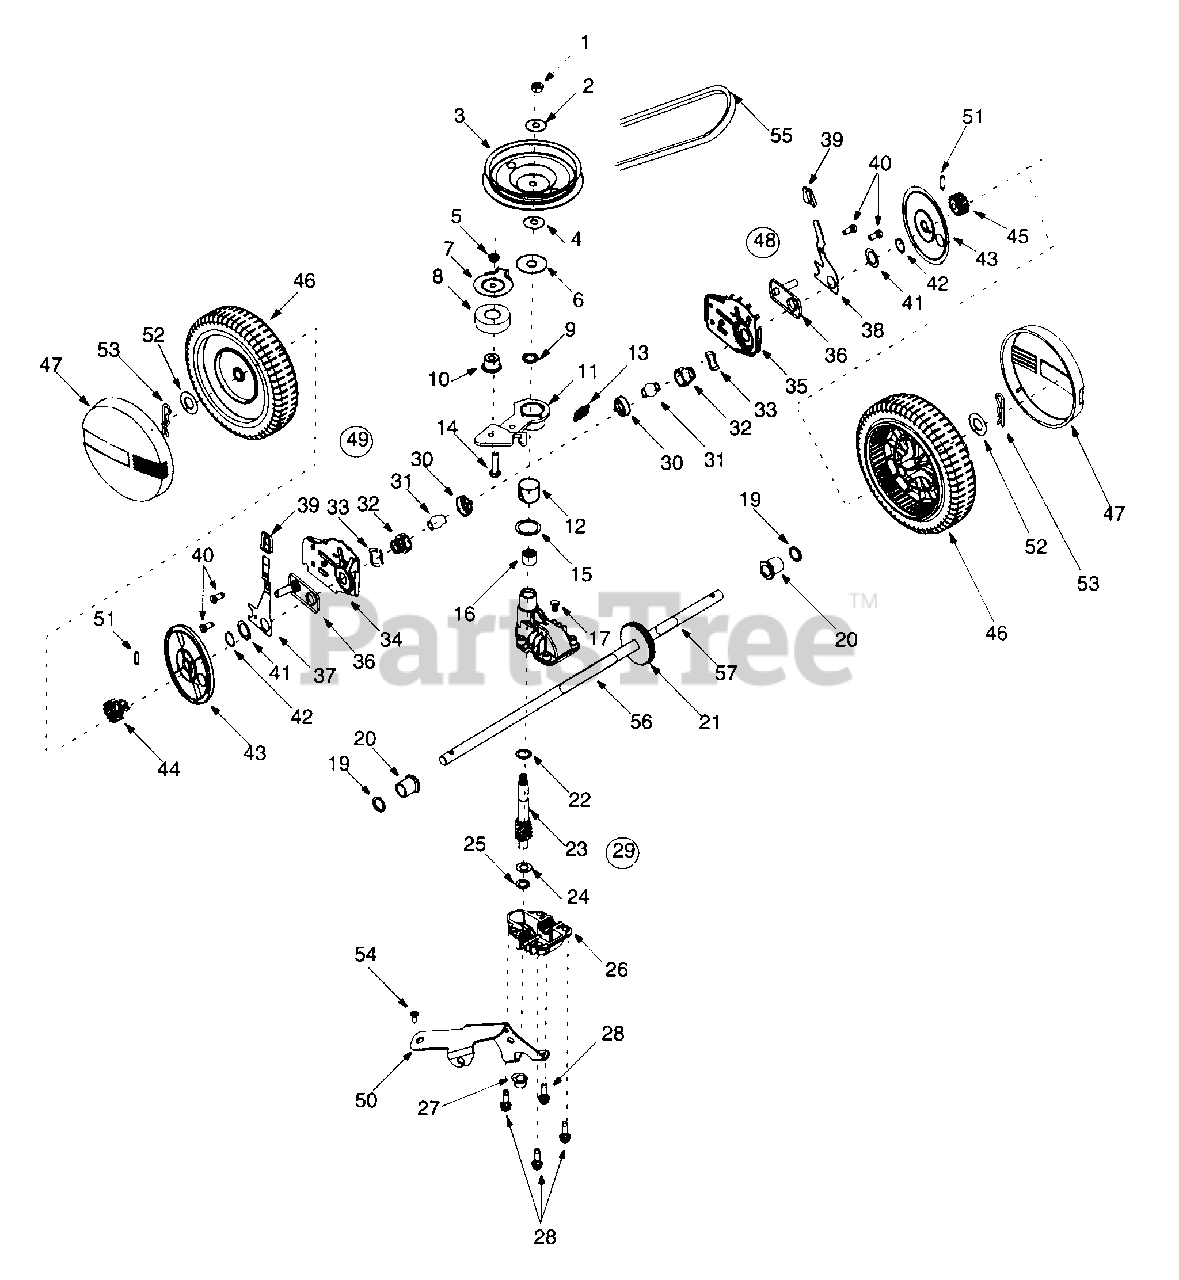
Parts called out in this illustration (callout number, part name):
1	Hex Jam Nut 5/16-24
2	Bell Washer .325 x .930 x .045
3	Pulley, 3.82 x .313 x .68
4	Bell Washer .325 x .930 x .045
5	Lock Nut 1/4-28
6	Flat Washer .442 x 1.38 x .060
7	Belt Keeper
8	Ball Bearing
9	Oil Seal
10	Flange Spacer
11	Idler Bracket Assembly
12	Bearing Sleeve
13	Flat Washer .504 x .700 x .030
14	Hex Cap Screw 1/4-28 x 1.00
15	Flat Washer .865 x 1.145 x .030
16	Needle Bearing .438 x .625 x .500
17	Plug 1/4 x .437
19	Oil Seal .500 x .687 x .094
20	Flange Bearing
21	Output Shaft
22	Flat Washer .504 x .700 x .030
23	Pinion Shaft 10T
24	Thrust Washer .375 x .70 x .030
25	Thrust Washer .388 x .625 x .062
26	Lower Housing
27	Flange Bearing .378 x .531 x .370
28	Hex Screw w/Washer 1/4-20 x .750
29	Transmission Assembly
30	Bearing Retainer
31	Bearing Sleeve .50 I.D.
32	Bearing Support
33	Wave Washer 1.5 x 1.0 x .029
37	RH Front Lever
38	LH Front Lever
39	Knob
40	Hex Cap Screw 3/8-16 x .75
41	Washer DD 1.5" O.D.
42	Snap Ring 1.0 dia.
43	Wheel Dust Cap
44	Gear 14T RH FWD
45	Gear 14T LH FWD
46	Wheel, 8x2 Yellow
47	Hubcap: Yellow
48	RH Height Adj. Complete
49	LH Height Adj. Complete
50	Cable Idler Bracket
51	Dowel Pin
52	Flat Washer 1/2 x 1.00 x .063
53	Cotter Pin .08 x 1.42
54	Screw
55	Belt
56	Sleeve Spacer .52 I.D. x 10.1" Lg.
57	Sleeve Spacer .52 I.D. x 2.1" Lg.
